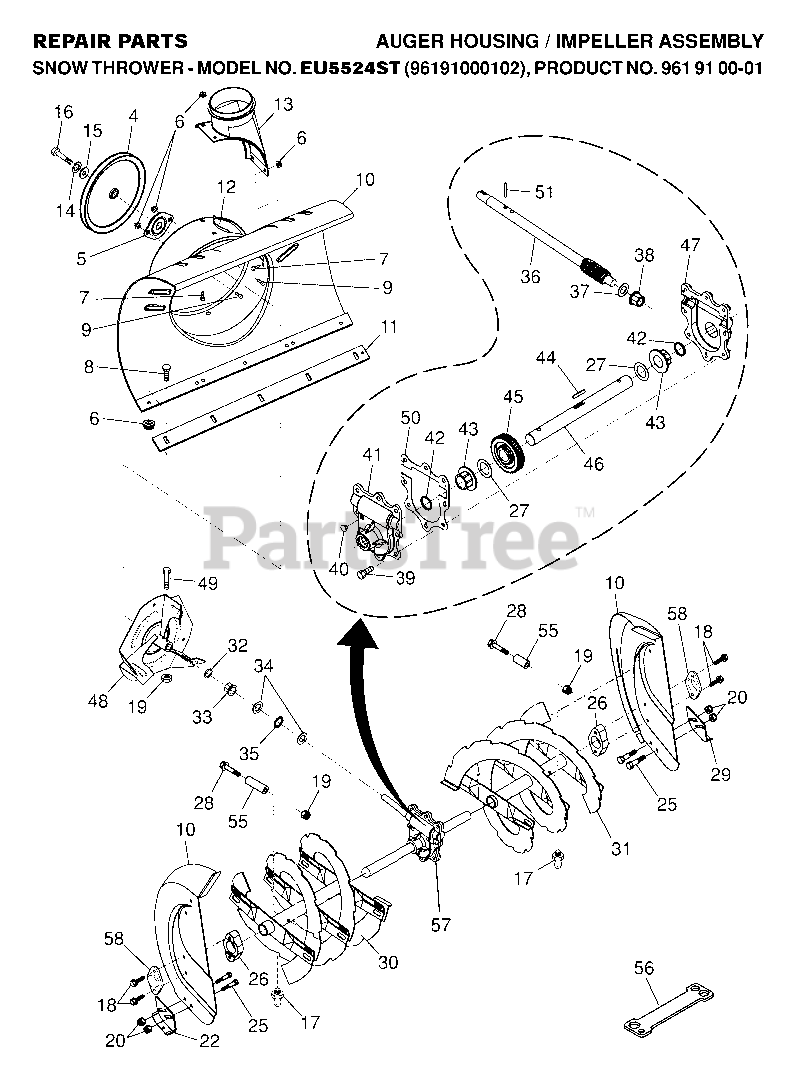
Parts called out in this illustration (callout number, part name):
4	PULLEY, IMPELLER
5	BEARING FLANGE
6	NUT, HEX FLANGE 5/16-18
7	BOLT.CARRIAGE.5/16-18X
8	BOLT
10	AUGER HOUSING
11	BAR, SCRAPER
12	BRACKET, CORNER DISCHARGE
13	BASE DISCHARGE CHUTE
14	WASHER.LOCK.HVY.HLCL.SPR.5/16
15	WASHER, FLAT
16	Screw, Hex Head 5/16-18 x 3/4
17	GREASE FITTING
18	SCREW, HEX HD 5/16X1
19	LOCKNUT.NYLOC.1/4-20
20	NUT, HEX FLANGE 5/16-18
22	SKID PLATE LH
25	BOLT
26	BEARING.BALL.AUGER.SHAFT
27	WASHER TRUST 1"
28	BOLT, SHEAR
29	SKID PLATE RH
30	RP AUGER ASSEMBLY, RH
31	RP AUGER ASSEMBLY, LH
33	BUSHING, FLANGE 3/4
34	WASHER, THRUST 3/4
35	BEARING TRUST 3/4 NTA-1220
36	SHAFT, IMPELLER
37	WASHER, THRUST 5/8
38	FLANGE BUSHING-5/8
39	HEX SCREW-5/16 X 3/4
40	CASE PLUG
41	GEARBOX HOUSING-RH
42	OIL SEAL
43	FLANGE BUSHING-1"
44	KEY, SQUARE 1/4 X .875
45	WORM GEAR
46	AUGER SHAFT
47	HOUSING.GEARBOX.LH(SERVICE)
48	IMPELLER ASSY
49	SCREW.HEX.HD1/4-20X
50	GEARBOX GASKET
51	PIN, ROLL 3/16 X 1-1/8
55	SPACER.3943.SLEEVE.250X.47
56	RP WRENCH, SNOWTHROWER
57	GEARBOX.ASSEMBLY.AUGER
58	BEARING RETAINER, PLASTIC
